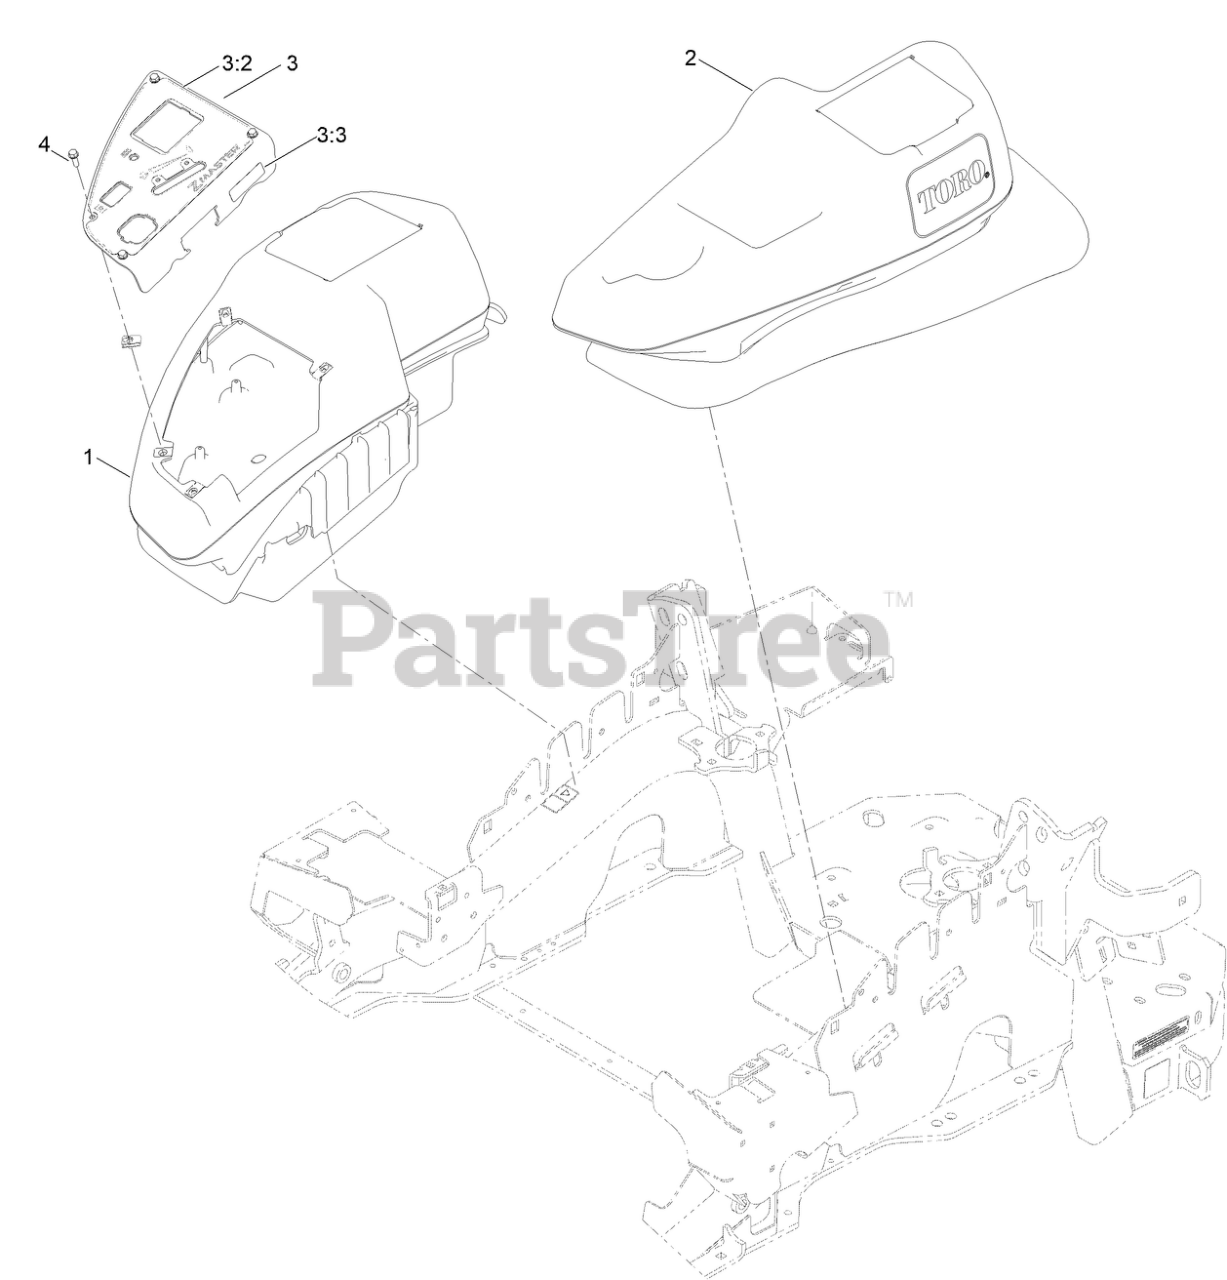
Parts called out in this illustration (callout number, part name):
1	RH CONSOLE ASM
2	LH CONSOLE ASM
3	CONTROL PANEL W/ DECAL ASM
3:2	DECAL-CONTROL PANEL
3:3	DECAL-FUSES
4	SCREW-HWH
